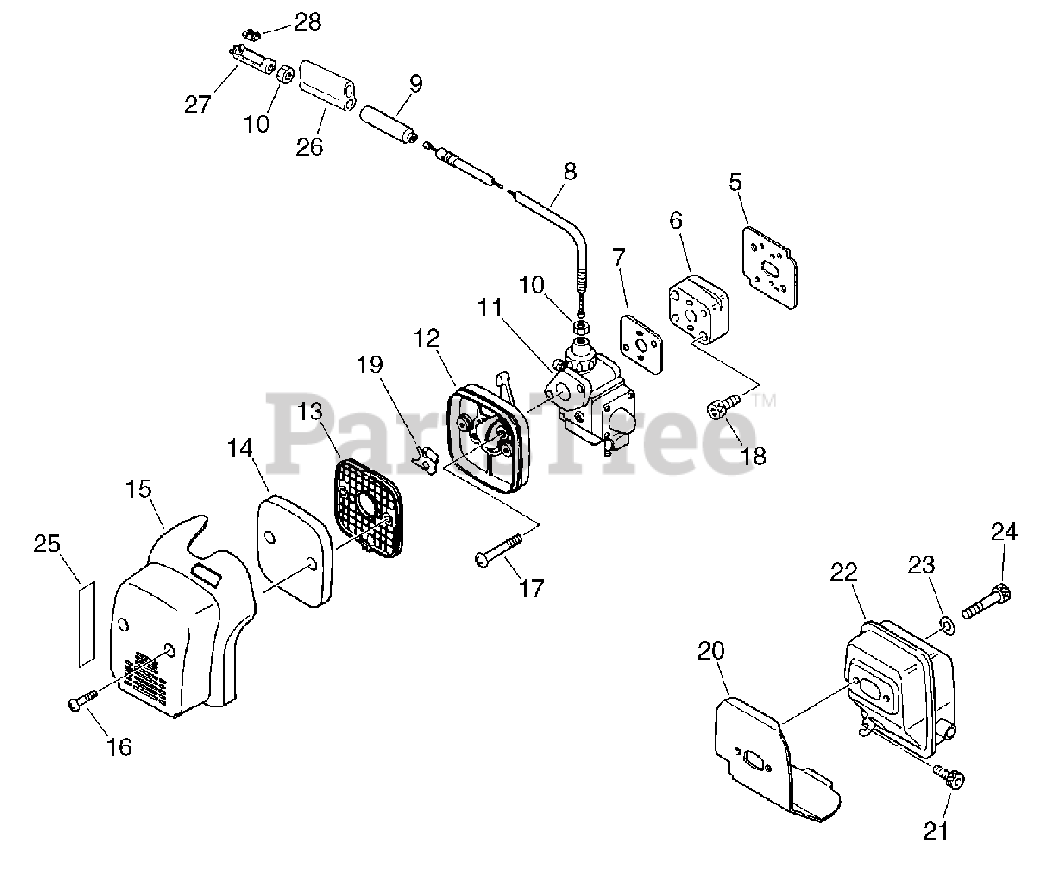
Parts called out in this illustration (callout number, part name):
5	GASKET, INTAKE
6	INSULATOR
7	GASKET
8	CABLE, THROTTLE
11	CARBURETOR
12	CASE, AIR FILTER
13	RETAINER, AIR FILTER
14	FILTER, AIR
15	COVER, AIR FILTER
16	SCREW 4×20
17	SCREW 5×50
18	BOLT 5×25
19	SPRING, CHOKE RETURN
20	GASKET, MUFFLER
21	BOLT 5×12
22	MUFFLER
22	MUFFLER ASSY
23	WASHER, FLAT 5.5×10×0.8
24	BOLT 5×60
25	LABEL, CHOKE
27	CONNECTOR
